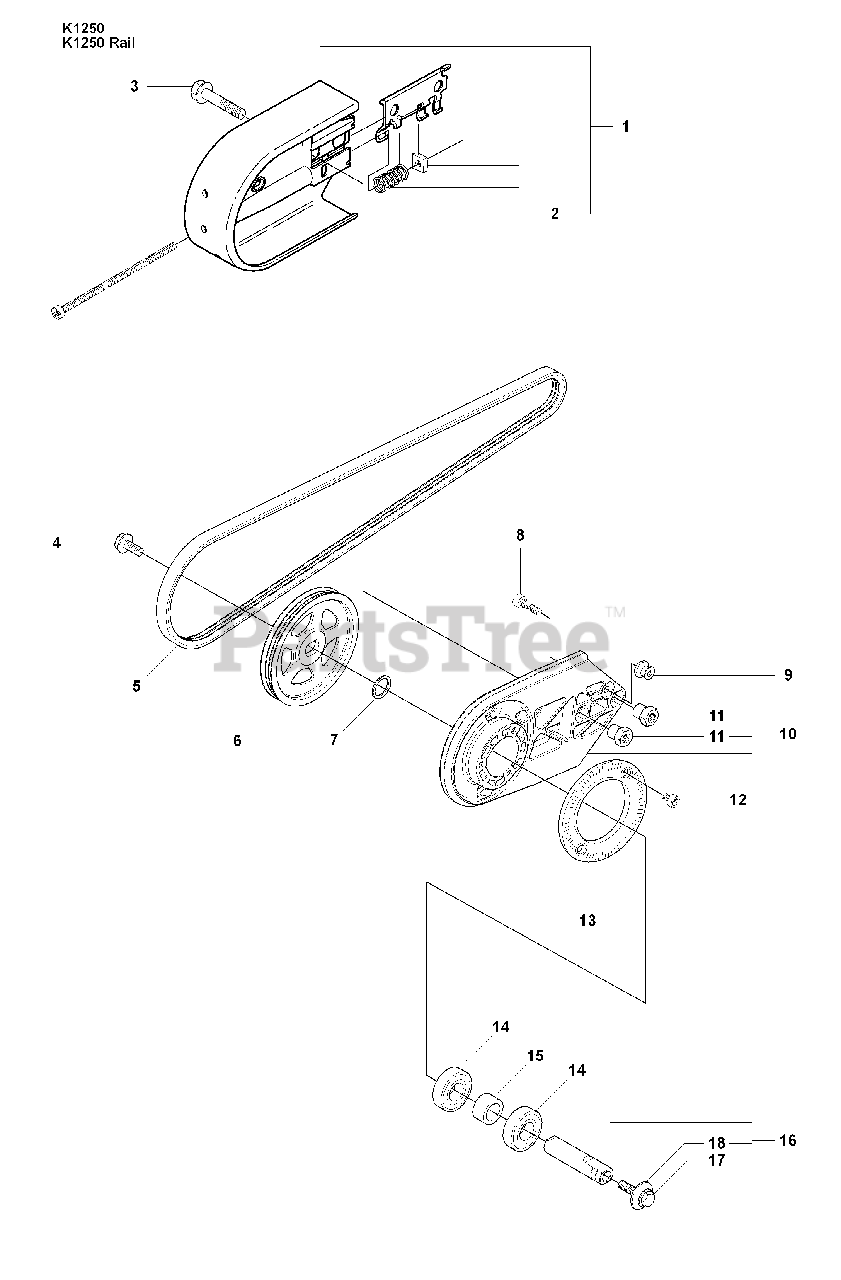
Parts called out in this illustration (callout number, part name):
1	BELT GUARD
2	BELT TENSIONER ASSY
3	COLLAR SCREW
4	SCREW COLLAR
5	BELT
6	PULLEY
7	WASHER STEEL
9	TORSION STOP
10	BEARING HOUSING
13	SCREEN PATTERN FLANG
14	BALL BEARING
15	SPACING SLEEVE
16	SHAFT
17	COLLAR SCREW
18	WASHER
